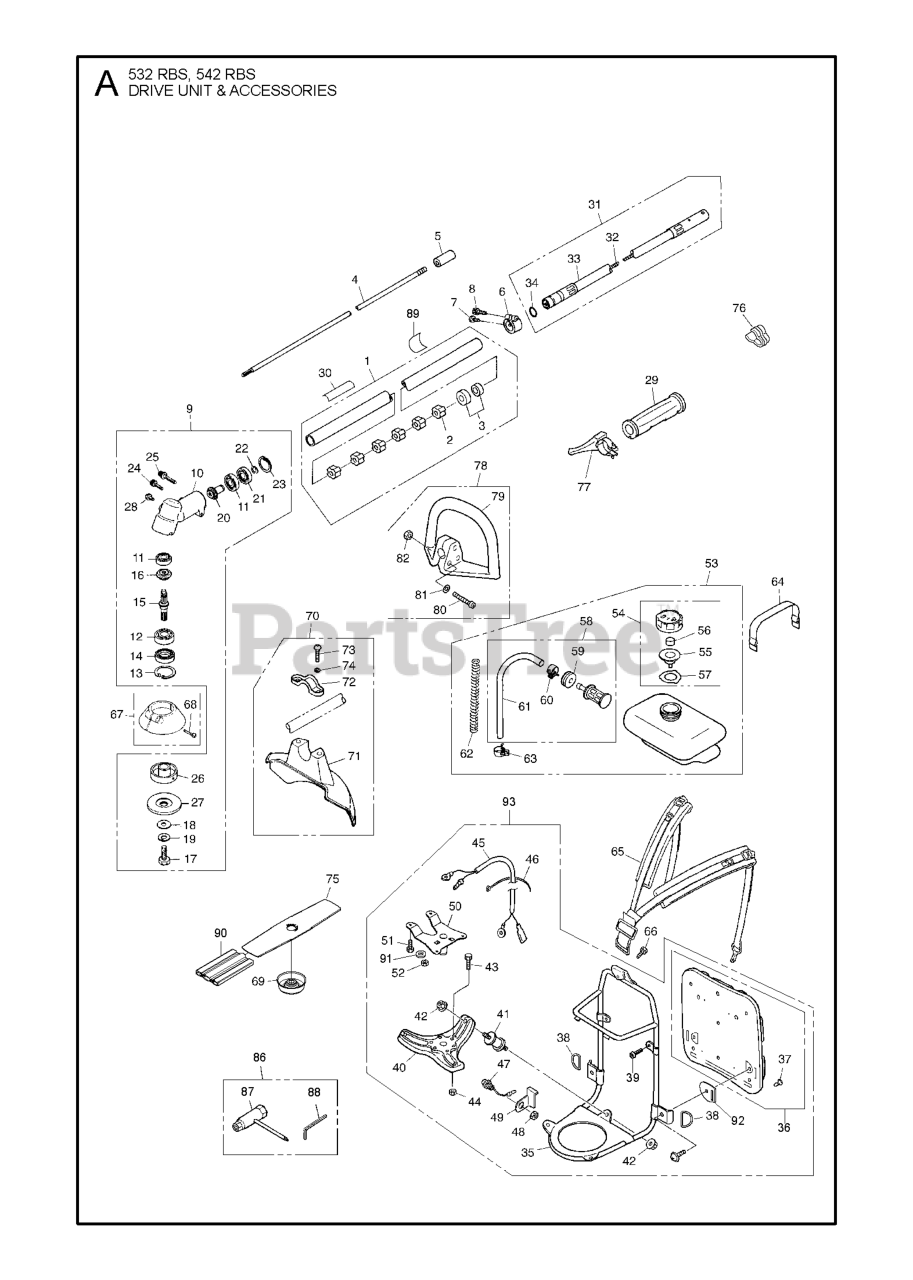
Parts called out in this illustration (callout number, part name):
1	PIPE COMP.(RPLS T321712100)
17	BOLT M8 X L25 L/H
21	BEARING,10MM ID,26MM OD,8MM W
22	RING, SNAP, M10 x 1.0
23	RING,SNAP M26x1.2 RP-318013340
25	BOLT M5 X L10 ALLEN BOLT
27	HOLDER (B)
30	LABEL CAUTION
53	TANK ASSY
66	BOLT M5 X L10 ALLEN BOLT
67	COVER ASSY
81	SCREW 0026000530
